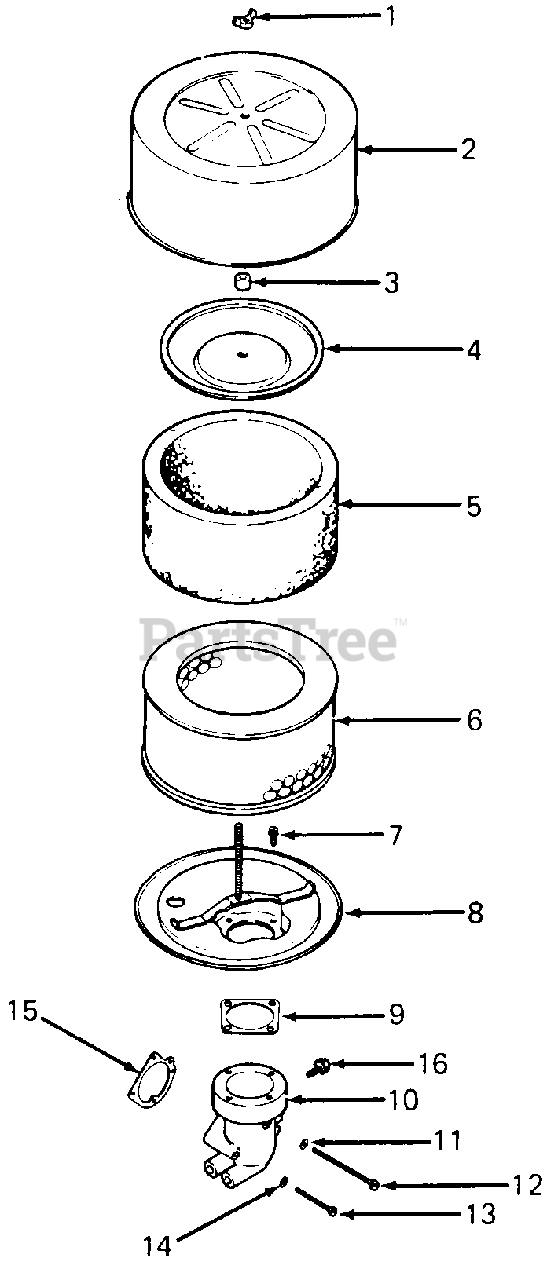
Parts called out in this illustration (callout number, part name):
1	Nut, Wing
2	Cover, Air Cleaner
3	Seal, Element Cover
4	Cover, Air Cleaner Element
5	Precleaner
6	Element
7	Screw, Hex Wash Hd, 10-32 X 9/16
8	Base, Air Cleaner
9	Gasket, Air Cleaner
10	Elbow, Air Cleaner
11	Washer, Plain, #10
12	Screw, Sltd Pan Hd, 10-32 X 2-1/4
13	Screw, Sltd Pan Hd, 10-32 X 1-1/2
14	Washer, I.T. #10
15	Gasket, Elbow
16	Screw, Self Tapping,1/4-20 X 5/8
